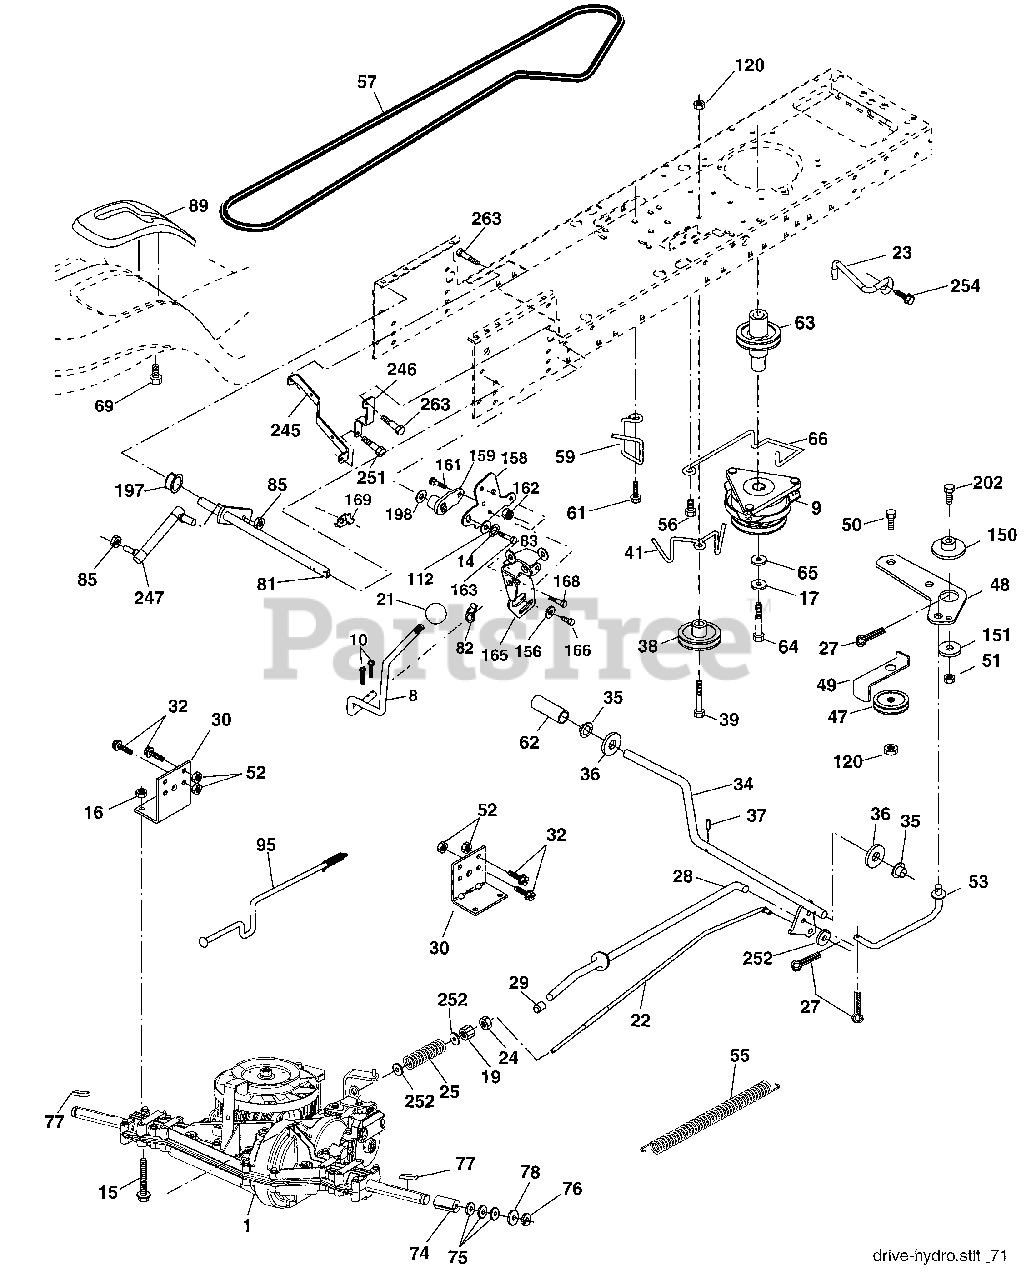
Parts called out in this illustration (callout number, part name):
8	Rod Shift Fender
9	Clutch Electric
10	Pin Cotter 1/8 x 1 CAD
14	Washer Lock Hvy Helical
15	Bolt Hex Flghd 5/16-18 Gr. 5
16	Nut Lock Hex W/Ins. 5/16-18 unc
17	Washer 1-1/2 OD x 15/32 ID x .250
19	Nut Lock Hex W/Wsh 3/8-16 unc
22	Rod, Brake Hydro
23	Bracket Anti-Rot
24	Locknut
25	Spring, Brake Rod
27	Pin Cotter 1/8 x 3/4 CAD.
28	Rod, Parking Brake
29	Cap, Parking Brake
30	Bracket, Transaxle
32	Bolt Hex Hd 5/16-18 unc x 3/4
34	Shaft, Foot Pedal Nibbed
35	Bearing, Nylon
37	Pin, Roll
38	Pulley, Idler, Flat Composite
39	Bolt 3/8-16 x 2-3/4 Gr. 5
41	Keeper, Belt Idler Fool-Proof
47	Pulley, Idler, V-Groove
48	Bellcrank Clutch Grnd Drv Stl
49	Retainer, Belt
50	Bolt Carr. SH 3/8-16 x 1-1/2 Gr. 5
52	Nut Crown Lock 5/16-18
53	Link, Clutch
55	Spring, Return, Clutch
56	Screw 3/8-16 x 1-1/4
57	V-Belt, Ground Drive
59	Keeper, Center Span
61	Screw 3/8-16 x .875
62	Cover, Pedal
63	Pulley, Engine
64	Bolt Hex 7/16-20 x 4 x Gr. 5
65	Washer
66	Keeper Belt Engine Hydro
69	Screw Hex Wsh Hi-Lo 1/4-1/2 unc
74	Spacer, Axle
75	Washer 25/32 x 1-1/4 x 16 Ga.
77	Key, Square
78	Washer 25/32 x 1-5/8 x 16 Ga.
81	Shaft Asm. Cross
82	Spring Torsion T/A
83	Washer 17/32 x 3/4 x 16 Ga.
85	Nut Lock Center 1/4-28
89	Console, Shift
95	Control Asm. Bypass Disconnect
112	Washer 9/32 x 3/4 x 10 Ga.
120	Nut Lock 3/8-16
150	Spacer Retainer
151	Washer 13/32 x 2 x 10 Ga.
156	Washer Srrted 5/16 ID x 1.125
158	Bracket Shift Mount
159	Hub Shift
161	Bolt Rdhd Sqnk 1/4-20 x 3/4 Gr. 5
162	Nut Crownlock 1/4-20 unc
163	Bolt Hex Fin 1/4-20 unc x 1 Gr. 5
165	Bracket Pivot Lever
166	Screw 5/16-18 x 5/8
168	Bolt Shoulder 5/16-18 x .561
169	Plate Fastening Lt\
197	Nyliner Snap-In 5/8" ID
198	Washer Nyliner 7/8 ID x .105
202	Bolt 3/8-16 x 1-3/4 Gr. 5
245	Strap Torque Lh
246	Strap Torque Rh
247	Link Shift Transaxle
251	Screw 5/16-18 x 1
252	Washer
254	Screw 3/8-16 x 1
263	Screw Hexwsh Thdr 3/8-16 x 3/4
